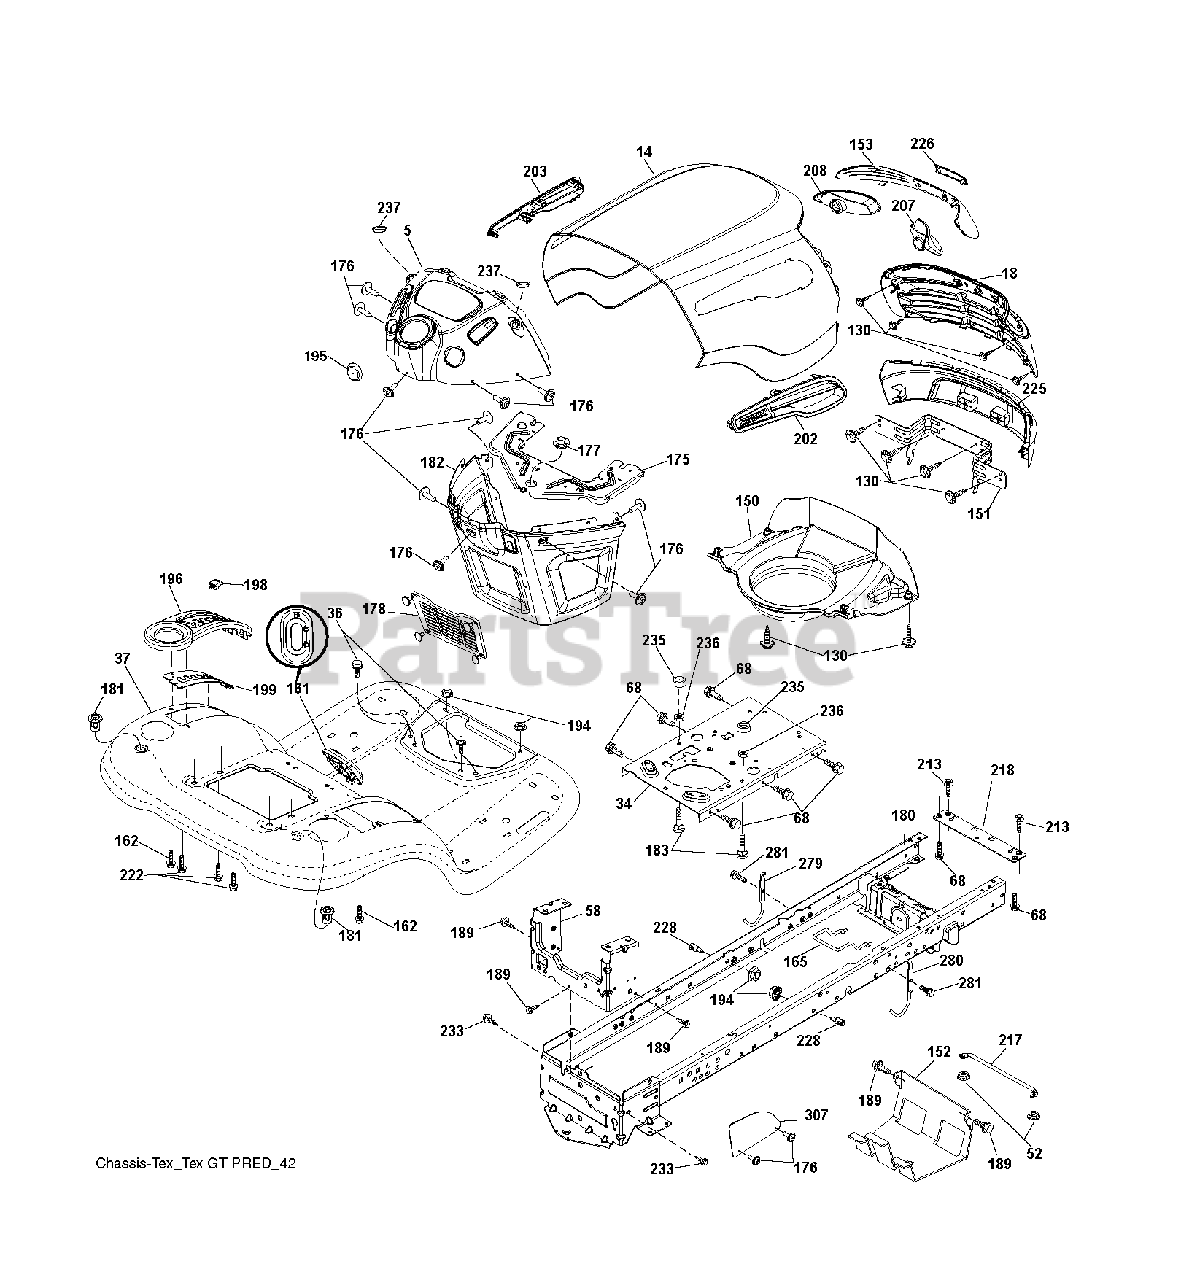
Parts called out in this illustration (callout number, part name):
34	PLATE.ENGINE.WELDED.CHASSIS
36	SCREW 5/16"
52	LOCKNUT
58	DRAWBAR.UPPER.2PC,LRG.FENDER
130	SCREW.#10 X 0.750.BOS THREAD
152	SHIELD BROWNING
161	CONSOLE.FUEL.WINDOW.STGT.BLACK
162	SCREW.HI-LO.CONSOLE
165	SUPPORT.TANK.REAR.W/TE
175	PLATE.CROSSMEMBER.HUSQ
176	SCREW.#10-24X5/8.RN.QU
177	BUSHING,STEERING
178	CARGO.ASM.NET.TXGT.W/C
180	CHASS.WLDMNT.TL.12GA/2P.48/54
181	FEND/FTRST.PCH.CPH.NFW
182	DASH.LOWER.COMMON.12V.ADAPTOR
183	BOLT.5/16-18X1-1/4 FULL THD
189	SCREW
194	NUT LOCK HEX FLANGE 5/16-18
195	PLUG.HOLE.DASH.LOWER.12V.BLK
198	INDICATOR DECK LIFT
199	PLATE DECK LIFT
213	BOLT
217	ROD.PIVOT.HOOD
218	X-PIECE.HOOD.STOP.NON/
222	SCREW.1/4-20X5/8
228	STUD.FASTNER.W/ANTI-ROTATE
233	BOLT.SHOULDER
235	SPACER FENDER
236	NUT.CENTERLOCK.5/16-
237	PLUG.MOUNT.CARGO.BLK
279	ROD UPSTOP
280	ROD UPSTOP
281	SCREW 3/8-16X1
